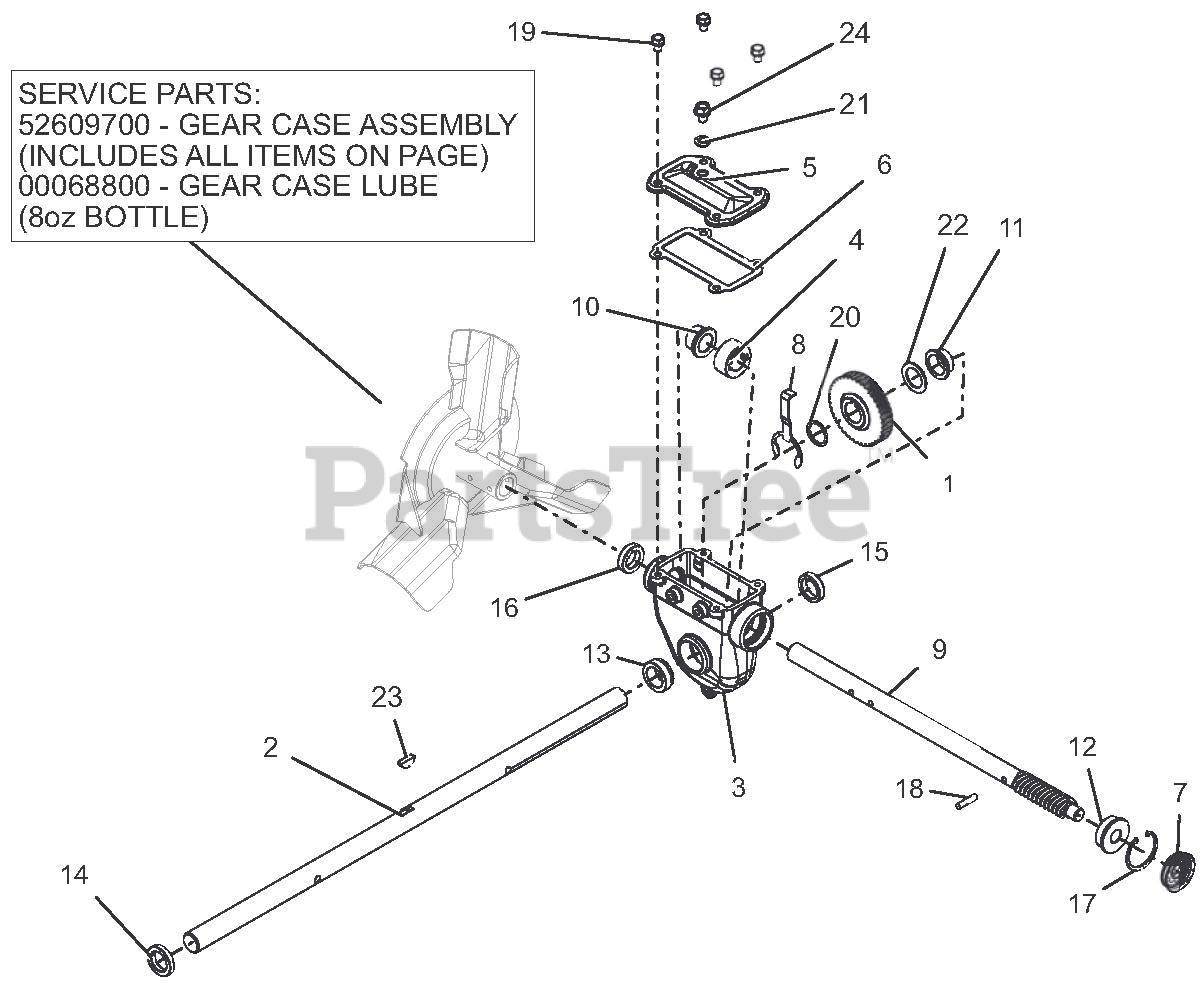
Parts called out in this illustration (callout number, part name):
1	WORM GEAR
2	SHAFT, RAKE-28"
3	GEARCASE, LARGE MACHINED
4	THRUST COLLAR, .875"ID SLIPFIT
5	COVER, TOP - LARGE IRON
6	GASKET, TOP - LARGE GEARCASE
7	COVER, GEAR CASE 1.75"
8	BUSHING RETAINER, LARGE
9	SHAFT, WORM - PRO
10	BSHG-FLG .879X1.128X.75X1.45
11	BSHG-FLG 1.006X1.128X.555X1.45
12	BSHG-FLG .628X1.503X.58X1.725
13	BSHG-FLG LARGE, RIGHT
14	SEAL-OIL .999X1.500X.250 TBC29
15	SEAL-OIL .999X1.375X.312 TBC29
16	SEAL-OIL .873X1.375X.312 TBC29
17	RG-RTNG-INT 1.750X.062
18	PIN-STR .250X1.12 6150
19	BOLT, SEMS .31-18X.50 GR5 YWZC
20	WSHR-FL-STL 1.010X1.250X.068YZ
21	WSHR-BND-SEAL .38X.75X.11 GALV
22	WSHR-FL-STL 1.010X1.505X.062YZ
23	KEY-WDRF .25X.875 HRD #A
24	@SCR-ROLOK .38-16X.50 HWH YWZC
25	GEAR CASE, 28" IRON PRO TOP-LD
26	ARIENS L3 LUBE, 8 OZ BOTTLE
